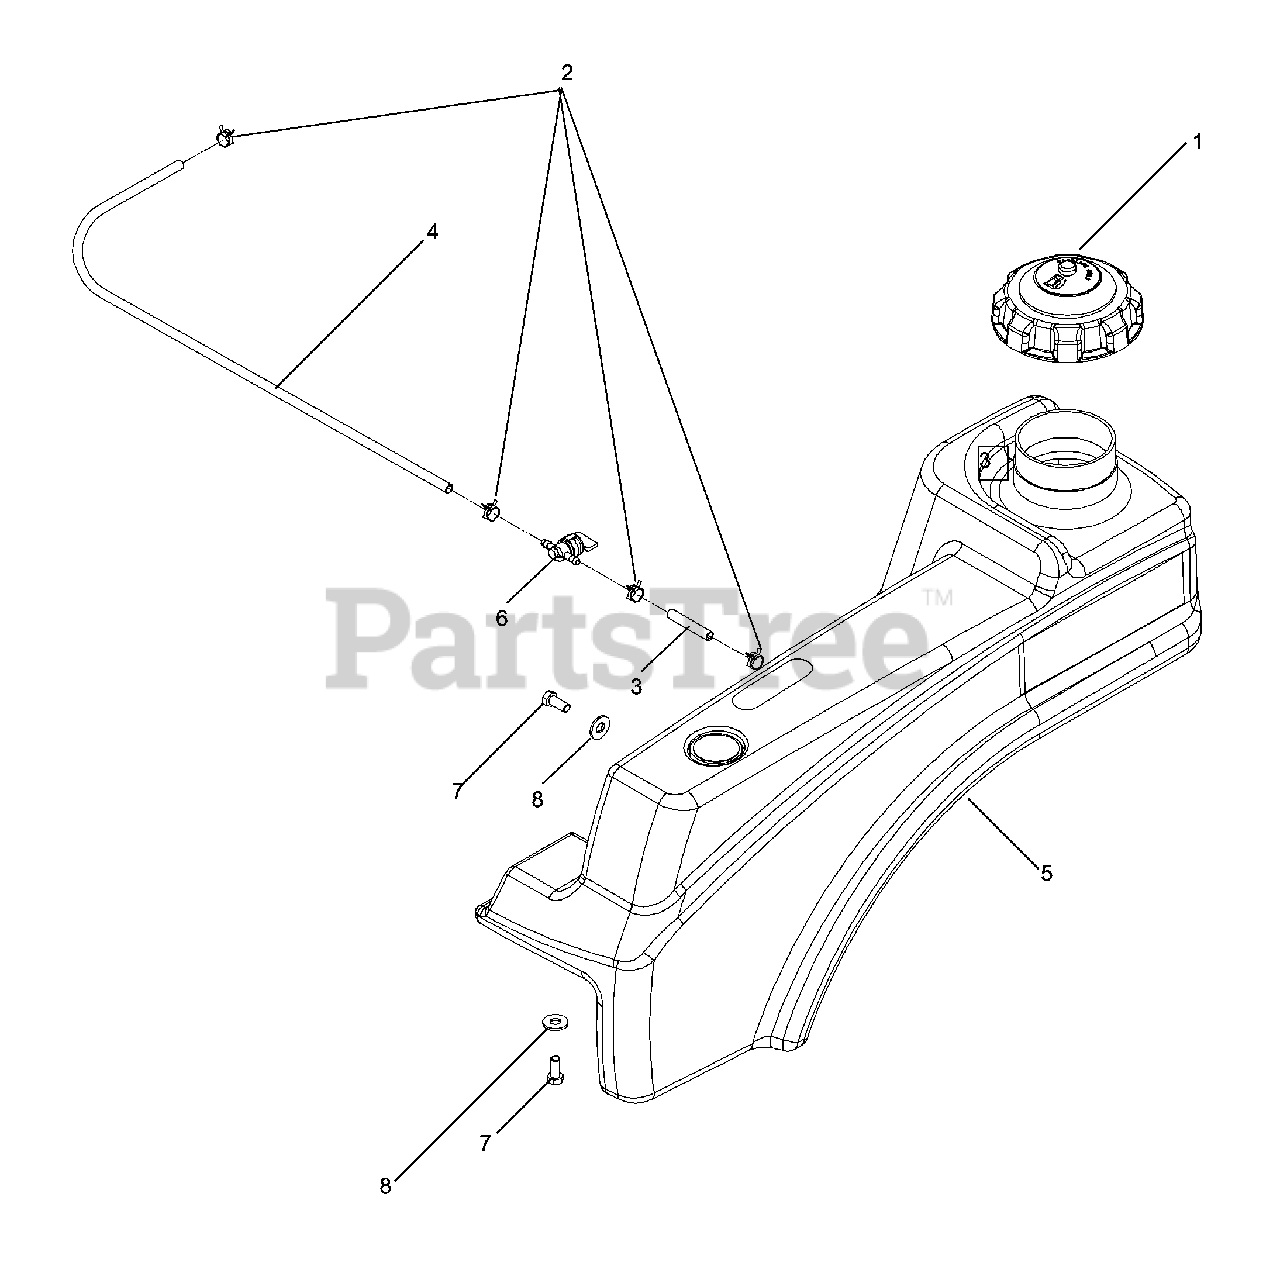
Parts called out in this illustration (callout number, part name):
1	FUEL CAP ANTI-SPLASH
2	HOSE CLAMP
3	HOSE 1/4 X 8
4	HOSE 1/4 X 28
5	FUEL TANK ASM.
6	SHUT OFF VALVE
7	HCS 5/16C X 3/4
8	FLAT WASHER 5/16 SAE
